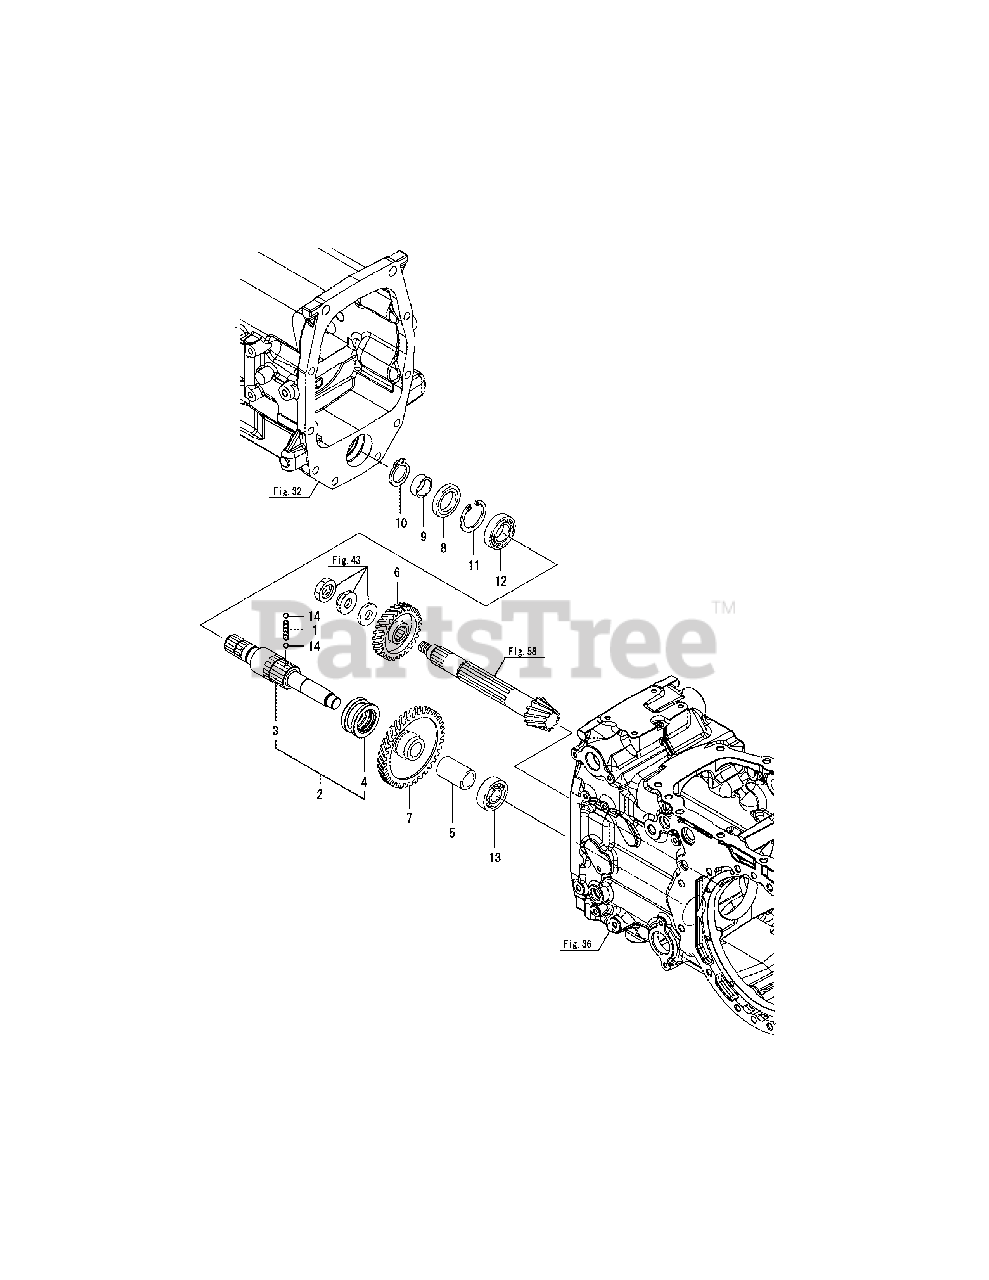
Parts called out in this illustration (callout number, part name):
2	SHAFT ASSY, DRIVE
3	SHAFT, FRONT DRIVE
6	PINION 33, DRIVE
7	GEAR,FRONT DRIVE 48
14	BALL 1/4, STEEL
